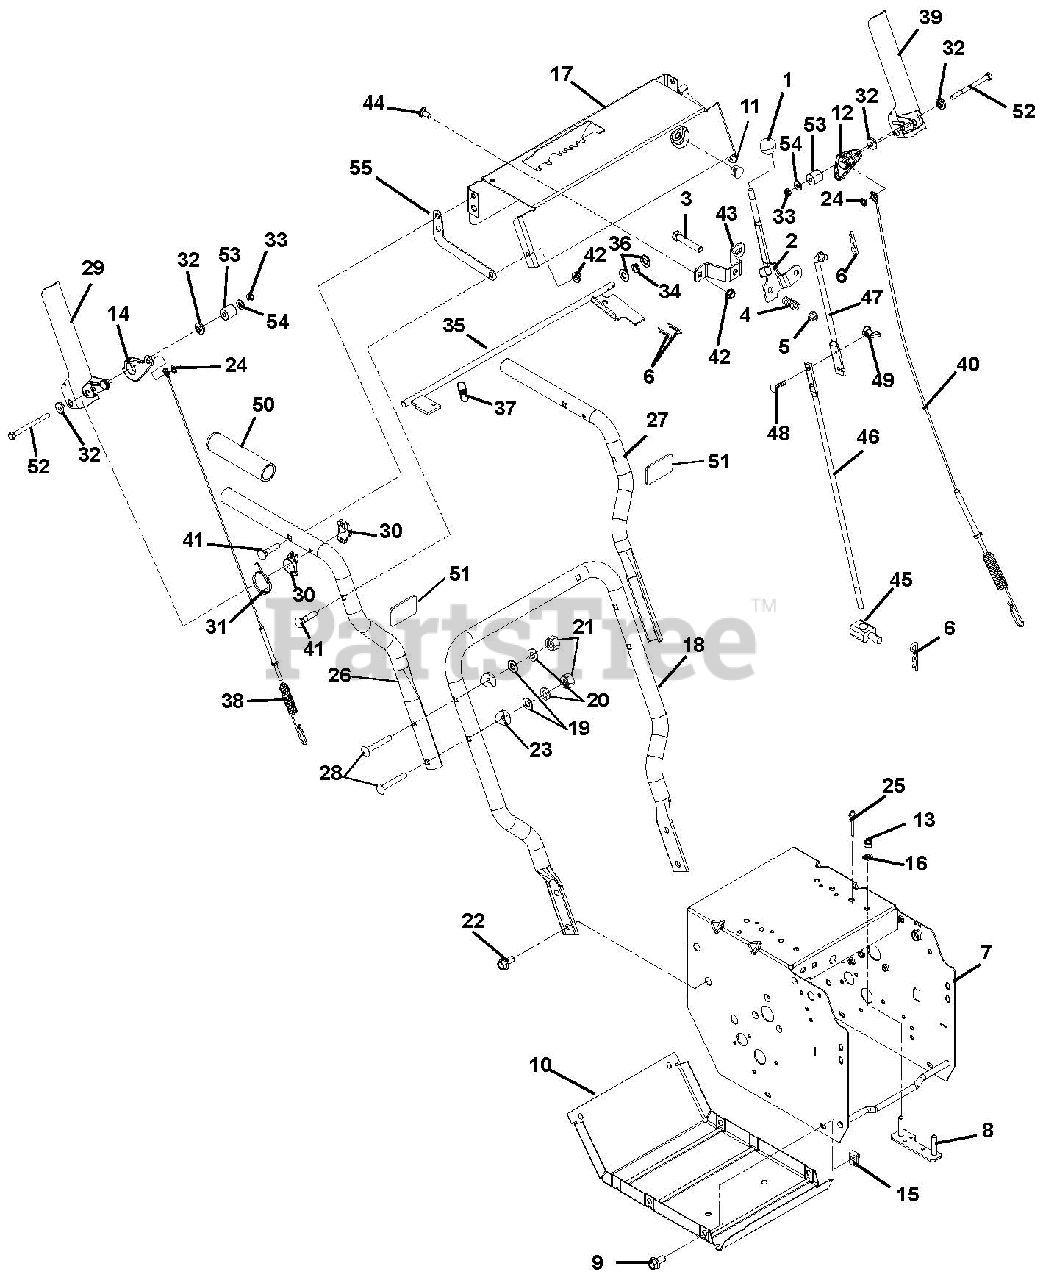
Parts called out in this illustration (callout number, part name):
1	KNOB,BALL -BLACK 1.47" .375-16
2	WMT, SHIFT LEVER
3	@BLT-HEX .38-16X2.00 GR5 YWZC
4	SG-COMP .125X.781X1.250
5	@NUT-LK-TOP-FLG .38-16 YWZC
6	PIN-HAIR INT .08X.18X1.18 YWZC
7	WELDMENT, FRAME
8	STRAP, ENGINE BOLT-WELDMENT
9	BLT-HEX .25-20X.75 HWH YZ GR5
10	COVER, BOTTOM
11	HOLE PLUG, PLASTIC .44 HOLE
12	CAM, INTERLOCK - LH
13	@NUT-HEX .31-18 YWZC
14	CAM, INTERLOCK - RH
15	NUT-RTNR .25-20X.56
16	WSHR-LK .312X.097 HVY YWZC
17	CONTROL PANEL W/DECAL
18	HANDLEBAR, LOWER - COMPACT
19	@WSHR-FL-STL.38X.875X.083 YWZC
20	@WSHR-LK .31X.078 REG YWZC
21	@NUT-LK-NYL .312-18 YWZC
22	BLT-SERHFWH .38-16X.75 YWZC
23	SPACER, HANDLEBAR
24	RG-RTNG-EXT .250X.010
25	RVT-POP .187 YZ
26	HANDLEBAR, UPPER - RH COMP/DEL
27	HANDLEBAR, UPPER - LH COMP/DEL
28	@BLT-RDHDSQNK .31-18X2.25 G5YZ
29	PADDLE, CLUTCH - RH COMPACT
30	SPACER, HANDLEBAR
31	SPRING, TORSION
32	BSHG, FLG .266X.42X.150 PM
33	NUT-JAM-NYL .250-20 W/INSERTYZ
34	BUSHING, POLYLINER-.38 SNAPIN
35	WELDMENT, INTERLOCK SHAFT
36	@WSHR-FL-STL.406X.812X.065 YWZ
37	SPRING, EXTENSION
38	CABLE, ATTACHMENT, COMPACT
39	PADDLE, CLUTCH - LH COMPACT
40	CABLE, TRACTION - COMPACT
41	BLT-RDHDXLSQNK .31-18X1.5 G5YZ
42	@NUT-LK-TOP-FLG .31-18 YWZC
43	BRACKET, SHIFT MOUNT
44	@BLT-RHDSSQNK .31-18X.62 G5YZ
45	PIVOT,SHIFT ROD .375-16(TRUNN)
46	ROD, SHIFT - LOWER
47	ROD, SHIFT - UPPER
48	@BLT-RDHDSQNK .25-20X.75 G5YZ
49	NUT-LK WING .250-20 YWZC
50	HANDLE GRIP
51	BUMPER PAD
52	@BLT-HEX .25-20X3.25 YWZC
53	BSHG, SLV .266 X .750 X .750
54	@WSHR-FL-STL.281X.62X.065 YWZC
55	STRAP, SUPPORT - DASH PANEL
